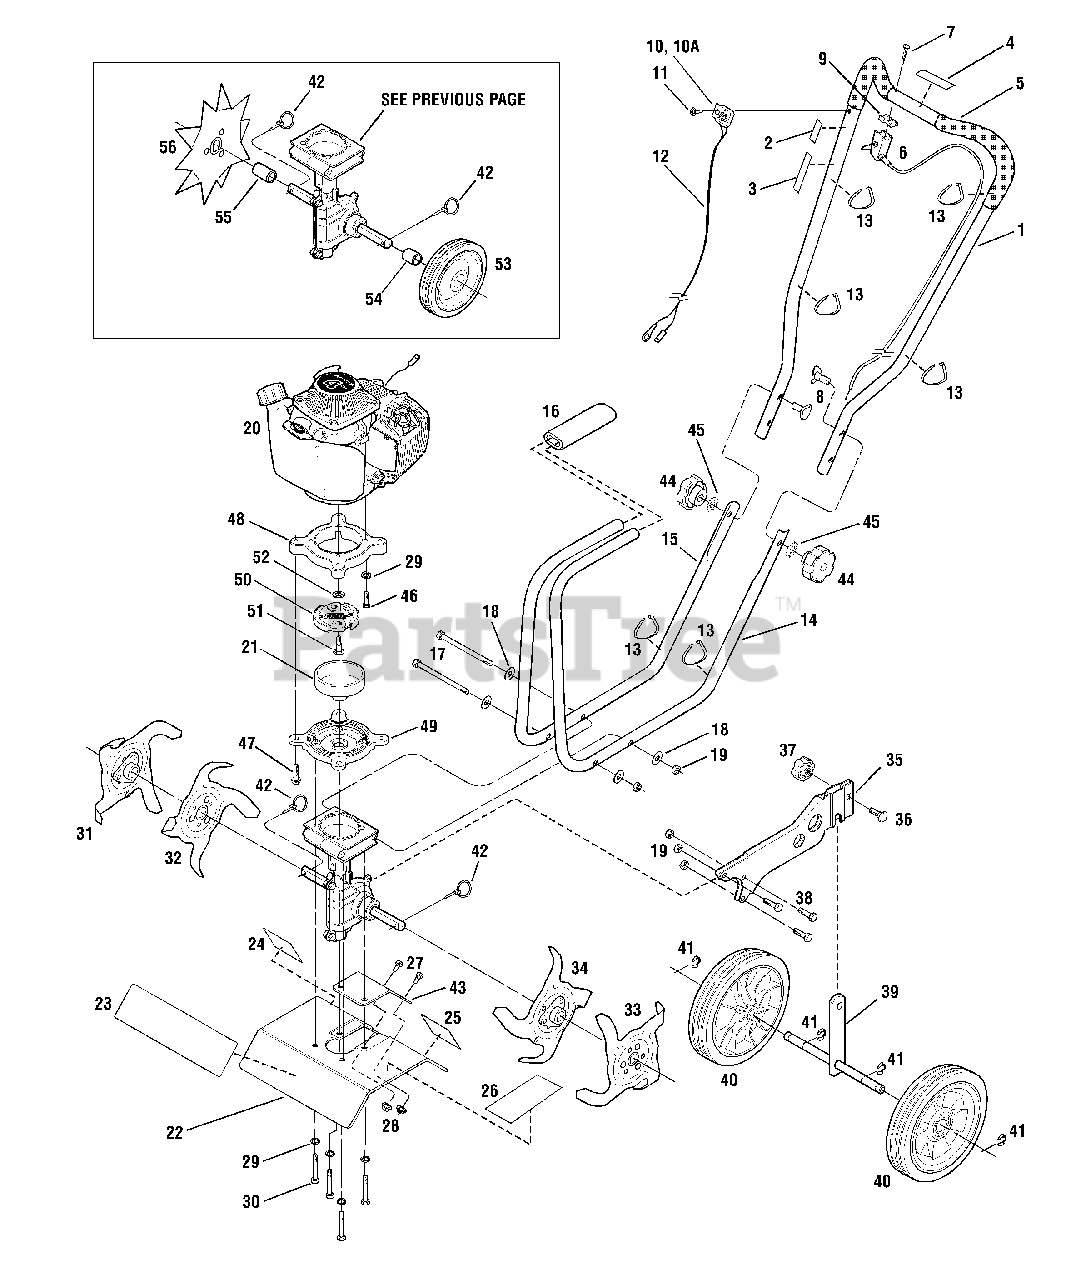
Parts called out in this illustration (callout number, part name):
1	Handlebar Assy.
2	Decal - On/Off Ignition Switch
3	Decal - Starting Stabilization
4	Decal - Throttle/Tines Control Lever Operation
5	Handlebar Grip, PVC
6	Throttle Lever and Cable
7	Pan Hd. Screw, #10-16 x 1-1/2
8	Saddle Hd. Screw, 5/16-18 x 2
9	Spacer, Throttle Lever
10	On/Off Ignition Switch
10A	Bracket - On/Off Ignition Switch
11	Phillips Hd. Screw, #12-24
12	Wire Assy. - On/Off Ignition Switch.
13	Plastic Wire Tie
14	Lower Handlebar - Left-Side
15	Lower Handlebar - Right-Side
16	Foam Sleeve
17	Hex Hd. Screw, 1/4-20 x 5
18	Flat Washer, 1/4-20
19	Hex Locknut, 1/4-20
20	Engine
21	Clutch Drum and Hub
22	Tine Shield
23	Decal - Logo
24	Decal - Warning, Rotating Tines
25	Decal - Warning, Hot Surfaces
26	Decal - Caution, Operation Hazards
27	Hex Hd. Screw, #10-24 x 1/2
28	Flange Locknut, #10-24
29	Lock Washer, 1/4-20
30	Hex Cap Screw, 1/4-20 x 2
31	Outer Tine - Right-Hand Side
32	Inner Tine - Right-Hand Side
33	Outer Tine - Left-Hand Side
34	Inner Tine - Left-Hand Side
35	Wheel Bracket
36	Carriage Bolt
38	Hex Hd. Screw, 1/4-20 x 1
40	Wheel
42	Ring Lock Pin
43	Tine Hood Cover
45	Lock Washer, 5/16
46	Hex. Hd. Screw, M6 x 20
47	Hex Flange Screw, 5/16-18 x 1-1/4
48	Adapter Plate - Engine
49	Adapter Plate - Transmission
50	Clutch Assy.
53	Edger Wheel
54	Bushing - Short
55	Bushing - Long
56	Edger Tine
